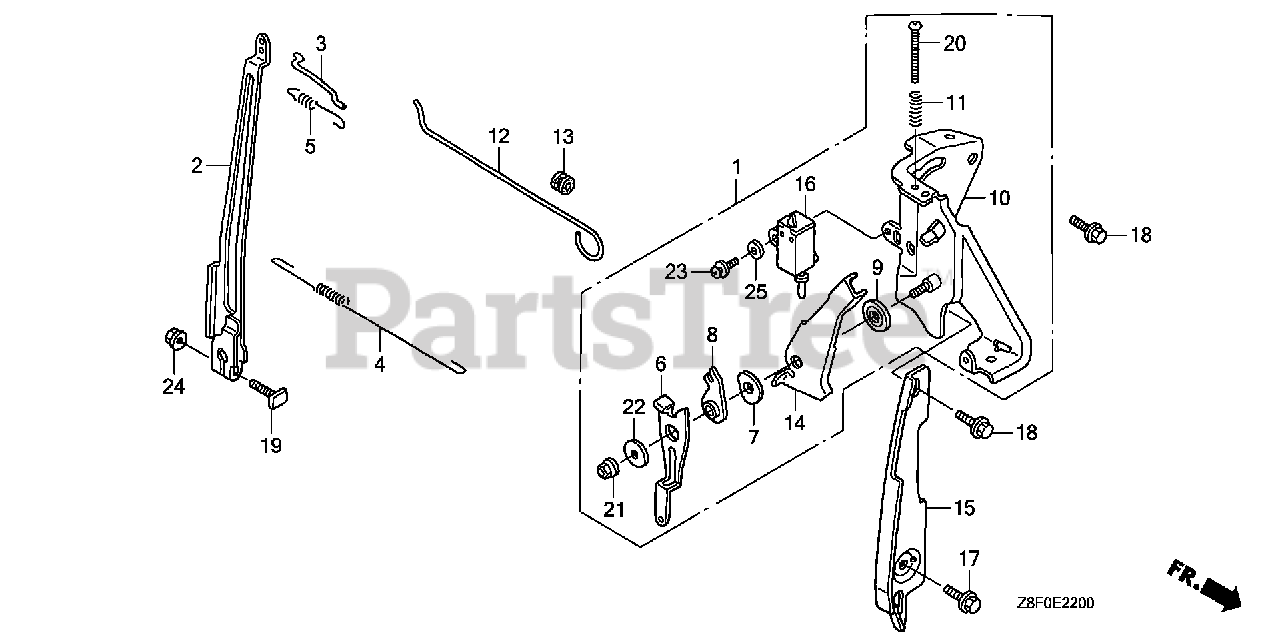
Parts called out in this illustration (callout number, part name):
1	CONTROL ASSY.
2	ARM, GOVERNOR
3	ROD, GOVERNOR
4	SPRING, GOVERNOR
5	SPRING, THROTTLE RETURN
6	LEVER, CONTROL
7	SPRING, LEVER
8	WASHER, CONTROL LEVER
9	SPACER, CONTROL LEVER
10	BASE, CONTROL
11	SPRING, CONTROL ADJUSTING Use from Engine SN 2327377.
12	ROD, CHOKE CONTROL
13	GROMMET, CHOKE ROD
14	LEVER, STOP
15	PLATE, SIDE
16	SWITCH ASSY., ENGINE STOP (N.O)
17	BOLT, FLANGE (6X13)
17	BOLT, FLANGE (6X12) (CT200)
18	BOLT, FLANGE (6X14)
19	BOLT, GOVERNOR ARM
20	SCREW, ADJUST
21	NUT, SELF-LOCK (6MM)
22	WASHER, WHEEL (6MM)
23	SCREW-WASHER (4X12)
24	NUT, FLANGE (6MM)
25	WASHER, PLAIN (4MM)
